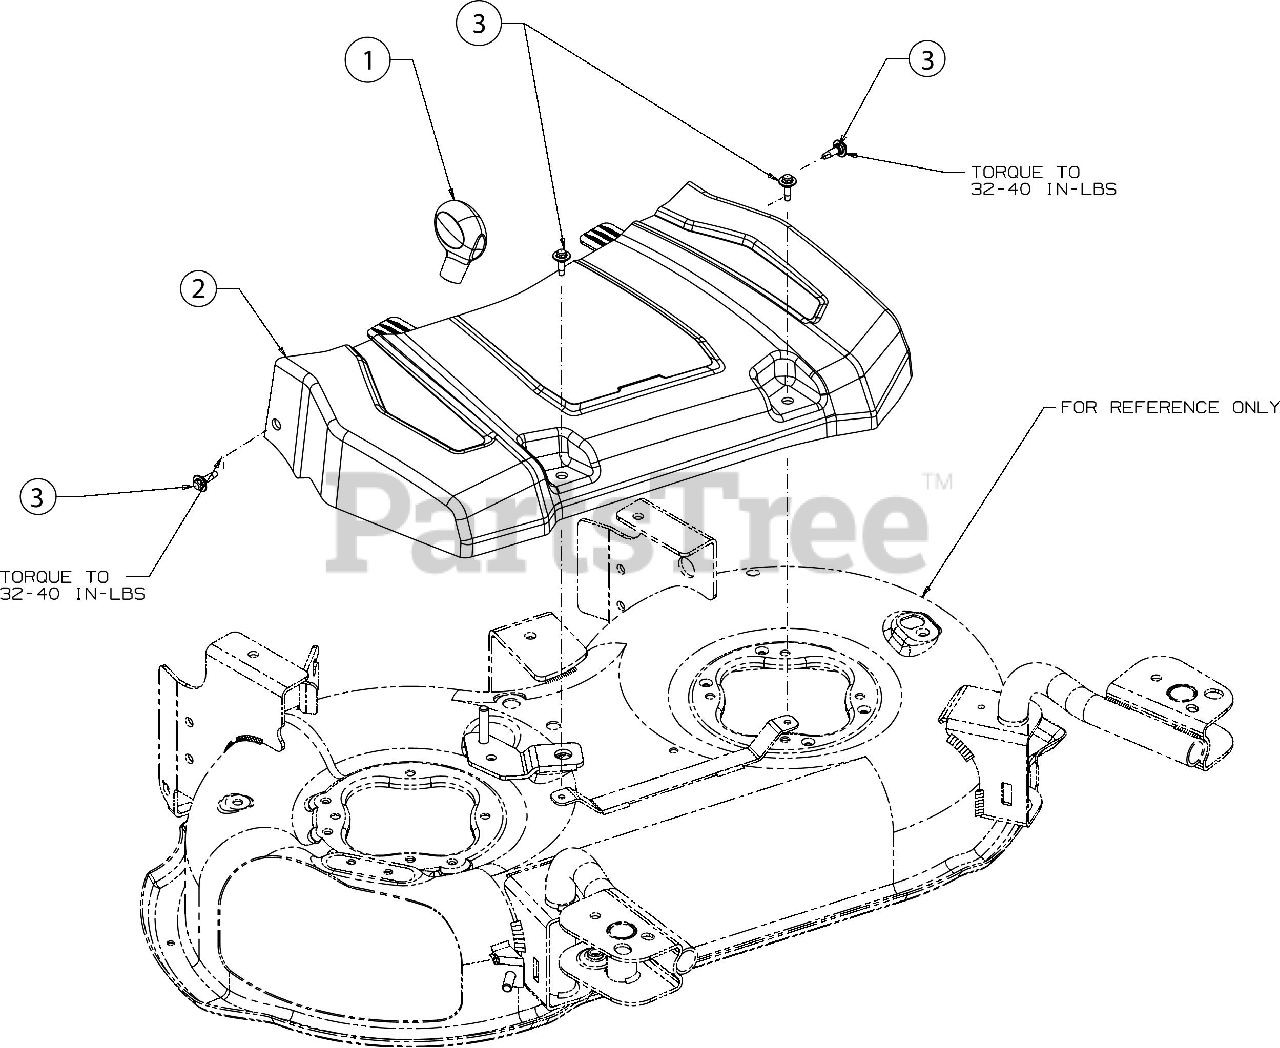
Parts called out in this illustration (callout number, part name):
1	HEIGHT ADJUSTMENT KNOB
2	28" BELT COVER
3	SHOULDER SCREW M6-1 .368 X.115
